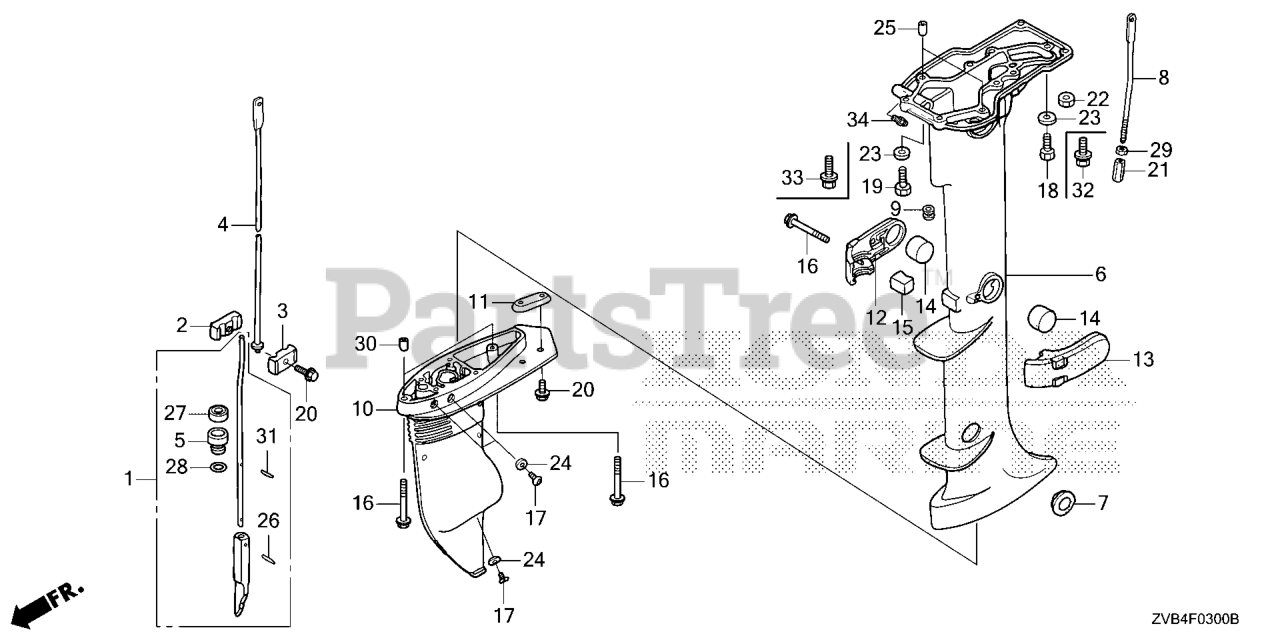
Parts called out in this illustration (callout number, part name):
1	ROD B, SHIFT
2	JOINT, R. SHIFT ROD
3	JOINT, L. SHIFT ROD
4	ROD A, SHIFT (S)
5	HOLDER, SEAL
6	CASE, EXTENSION *NHB14M* (S) (AQUA MARINE SILVER METALLIC)
6	CASE, EXTENSION *NHB14M* (S) (AQUA MARINE SILVER METALLIC) (NOT AVAILABLE)
7	GROMMET, EXTENSION
8	SHAFT, REVERSE LOCK
9	GROMMET, LOCK SHAFT
10	CASE, GEAR *NHB14M* (AQUA MARINE SILVER METALLIC)
11	METAL, ANODE
12	HOUSING, R. MOUNTING (LOWER) *NHB14M* (AQUA MARINE SILVER METALLIC)
13	HOUSING, L. MOUNTING (LOWER) *NHB14M* (AQUA MARINE SILVER METALLIC)
14	RUBBER A, MOUNTING (LOWER)
15	RUBBER B, MOUNTING (LOWER)
16	BOLT-WASHER (6X50)
17	BOLT, OIL CHECK
18	BOLT, HEX. (6X32)
19	BOLT, HEX. (6X40)
20	BOLT, FLANGE (6X16)
21	NUT, REVERSE LOCK
22	NUT, HEX. (6MM)
23	WASHER, PLAIN (6MM)
24	WASHER, NYLON (8MM)
25	PIN, DOWEL (8X16)
26	ROLLER (2.5X11.8)
27	SEAL, WATER (6MM)
28	O-RING (10.8X2.4) (ARAI)
29	NUT, HEX. (5MM)
30	PIN A, DOWEL (8X14)
31	PIN, SPRING (2.5X10)
32	BOLT-WASHER (6X32)
33	BOLT-WASHER (6X40)
34	NIPPLE, GREASE
